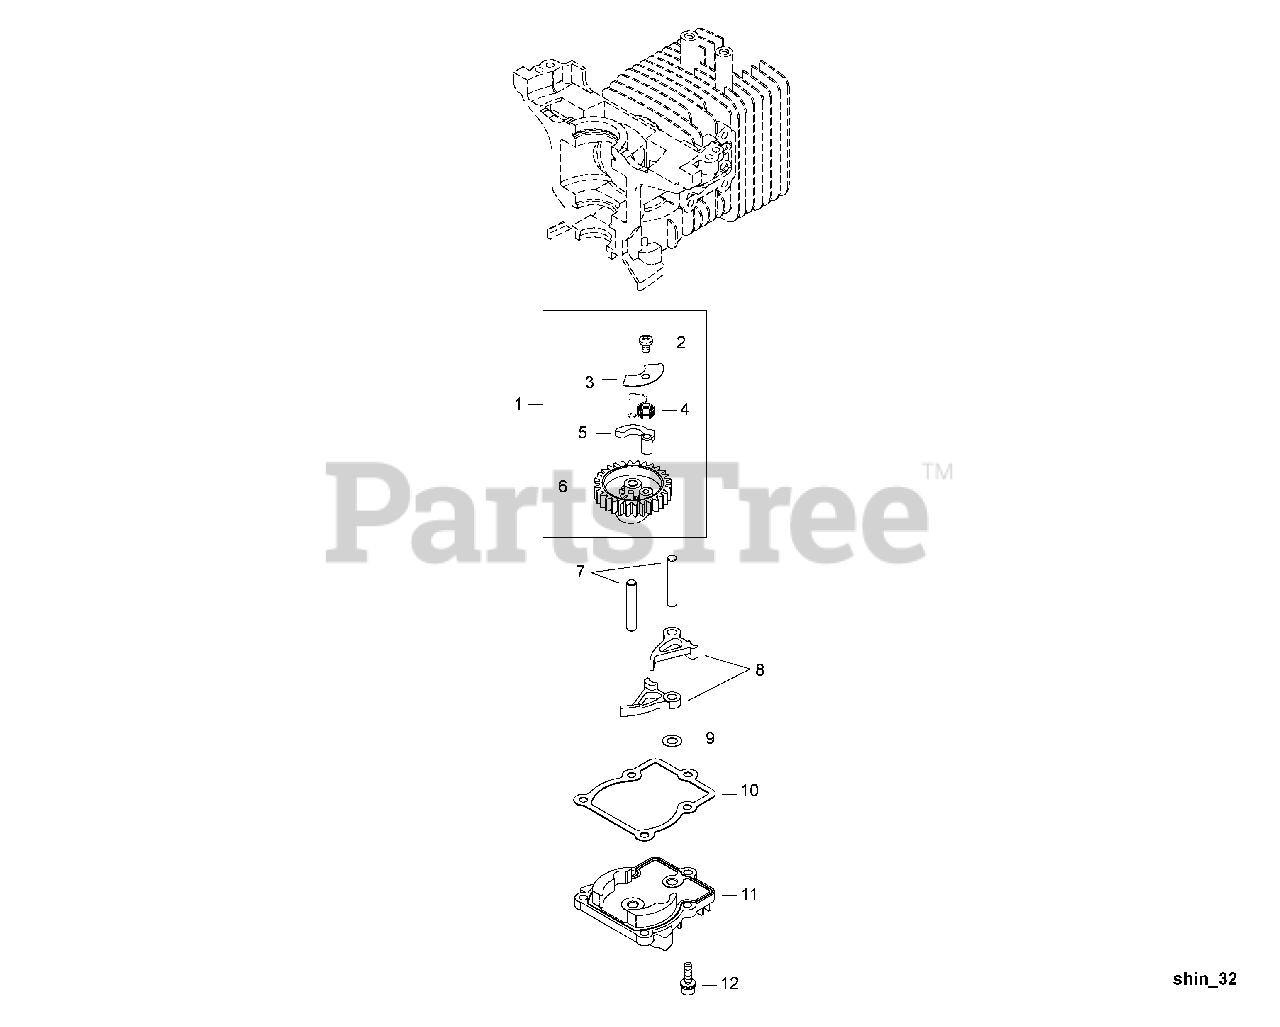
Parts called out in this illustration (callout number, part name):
1	CAM GEAR ASSY
2	SCREW - 4X6 -- TAPPING
3	PLATE, COVER
6	GEAR, CAM
8	FOLLOWER, CAM
9	WASHER - 5
11	COVER, CAM GEAR
12	SCREW - 4X14
